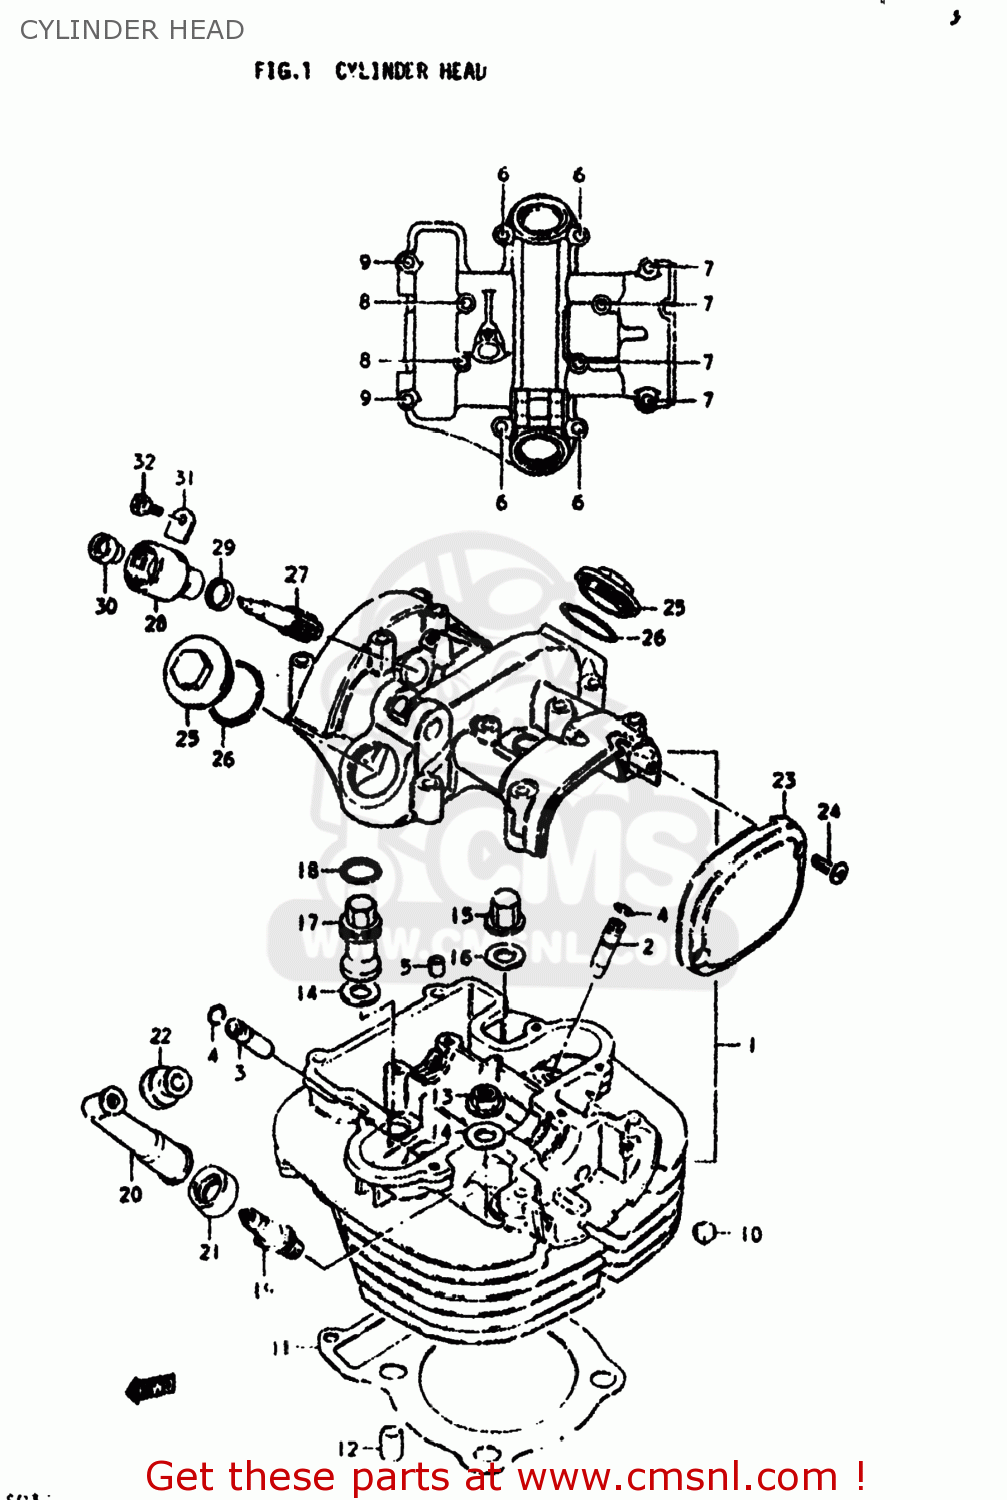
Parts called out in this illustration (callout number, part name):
1	HEAD ASSEMBLY,CYLINDER
2	GUIDE,VALVE
3	GUIDE,VALVE
4	RING,SNAP
5	PIN(6.2X8X11)
6	BOLT 6X35
7	BOLT
8	BOLT 6X65
9	BOLT
10	PAD,CYLINDER
11	GASKET,CYLINDER HEAD (NAS)
12	PIN
13	NUT
14	WASHER(10.5X22X2.3)
15	NUT
16	GASKET(10.5X22X2) (NAS)
17	NUT,CYLINDER HEAD SEAL
18	O RING(D:2.4,ID:17.8)
19	SPARK PLUG D8EA
20	CAP ASSY,SPARK PLUG
21	SEAL,SPARK PLUG
22	SEAL,SPARK PLU
23	CAP,CONTACT BREAKER
24	SCREW
25	CAP,INSPECTION
26	O RING(D:3,ID:29.5)
27	GEAR,TACHOMETER DRIVEN
28	SLEEVE,TACHOMETER DRIVE
29	SEAL,TACHOMETER DRIVEN
30	SEAL
31	PLATE,TACH DRIVE GEAR SLEEVE
32	SCREW(5X12)
